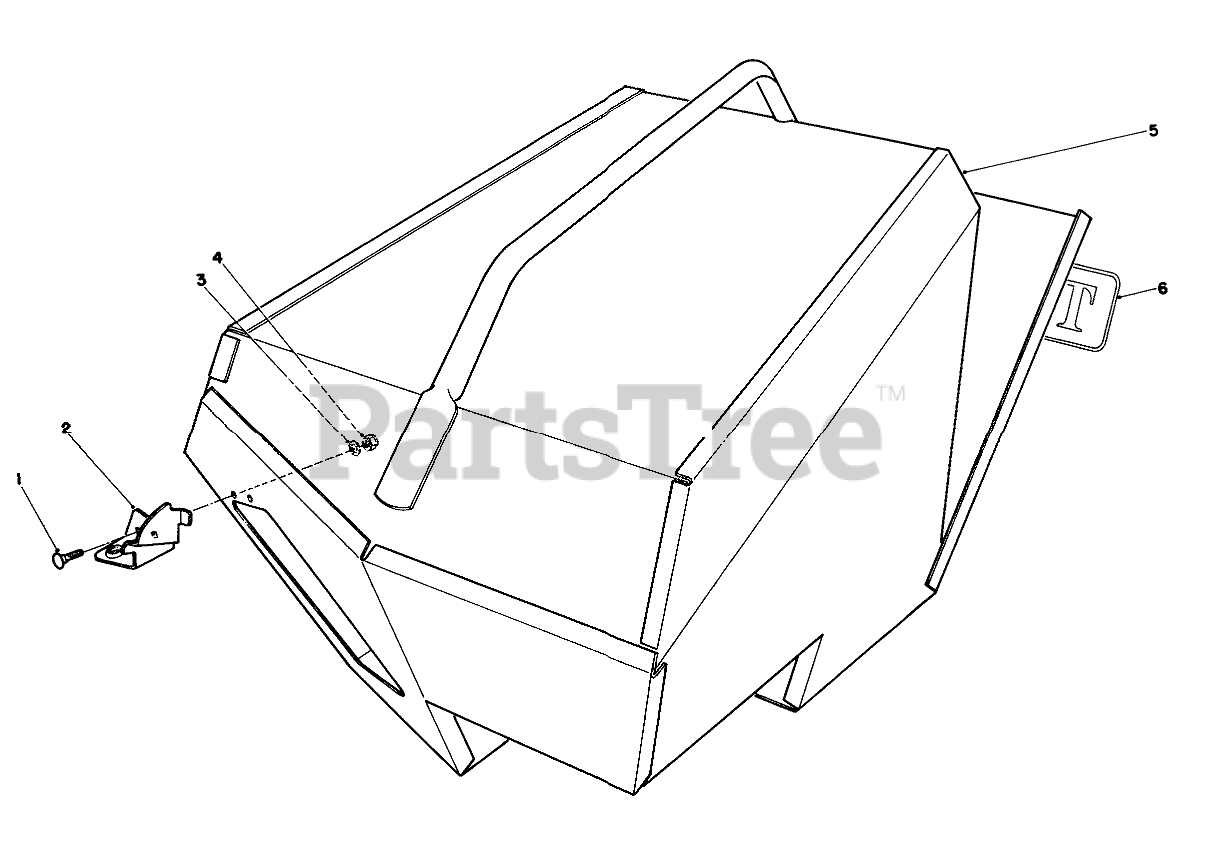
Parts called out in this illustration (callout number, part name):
1	SCREW-CARR
2	Bracket-Latch
3	WASHER-FLAT
4	NUT-LOCK, NI
5	Bag-Steel
6	Decal
